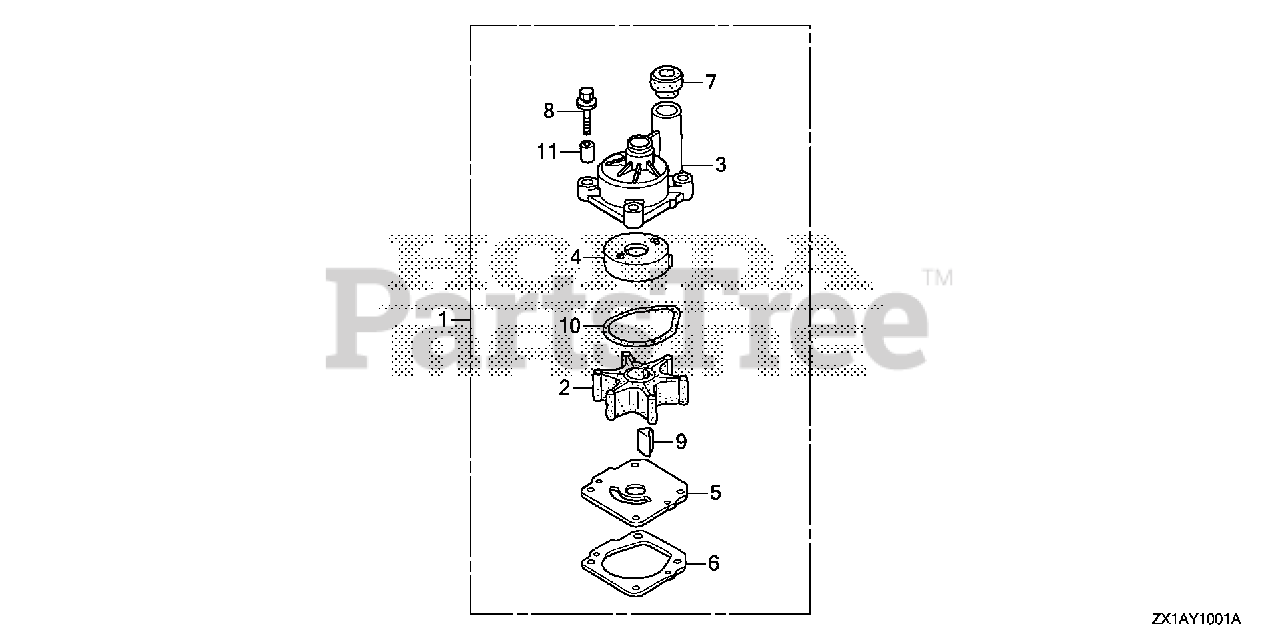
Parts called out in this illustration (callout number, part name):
1	PUMP KIT, IMPELLER
2	IMPELLER, PUMP
3	HOUSING, IMPELLER
4	LINER, PUMP
5	COVER, IMPELLER
6	GASKET B, IMPELLER
7	RING, WATER TUBE SEAL
8	BOLT-WASHER (8X40)
9	KEY, WOODRUFF
10	O-RING, WATER PUMP
11	COLLAR, DISTANCE
